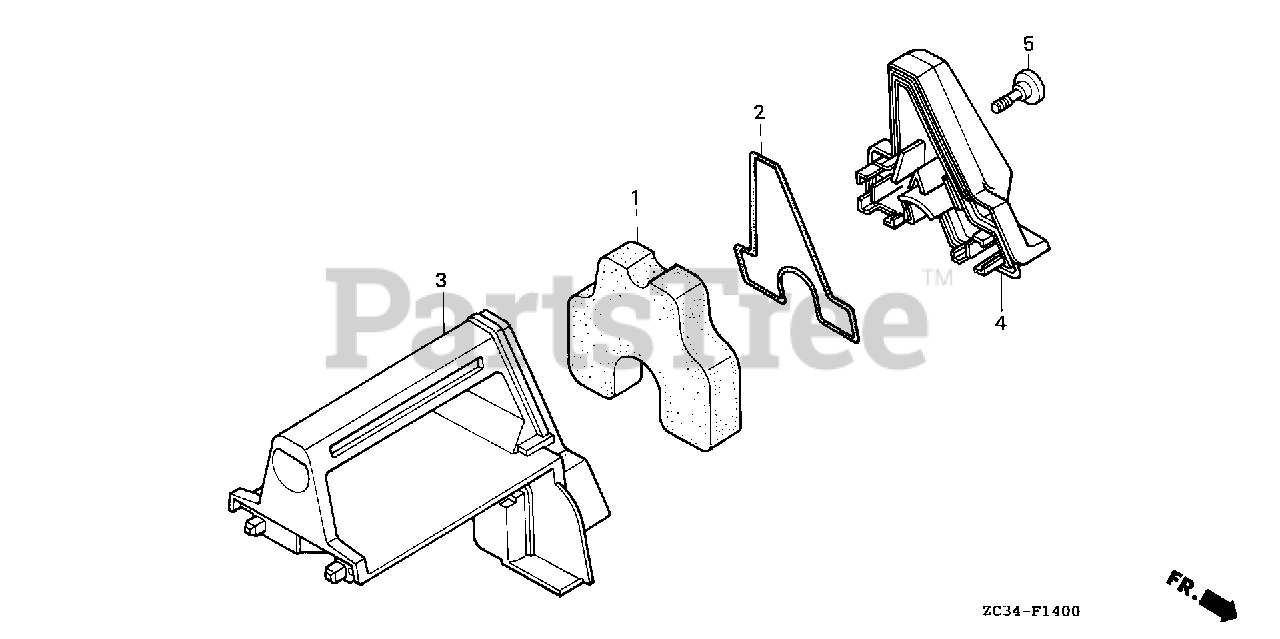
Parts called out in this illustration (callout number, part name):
1	ELEMENT, AIR CLEANER
2	SEAL, AIR CLEANER COVER
3	HOUSING, AIR CLEANER
4	COVER, AIR CLEANER
5	BOLT, AIR CLEANER COVER
